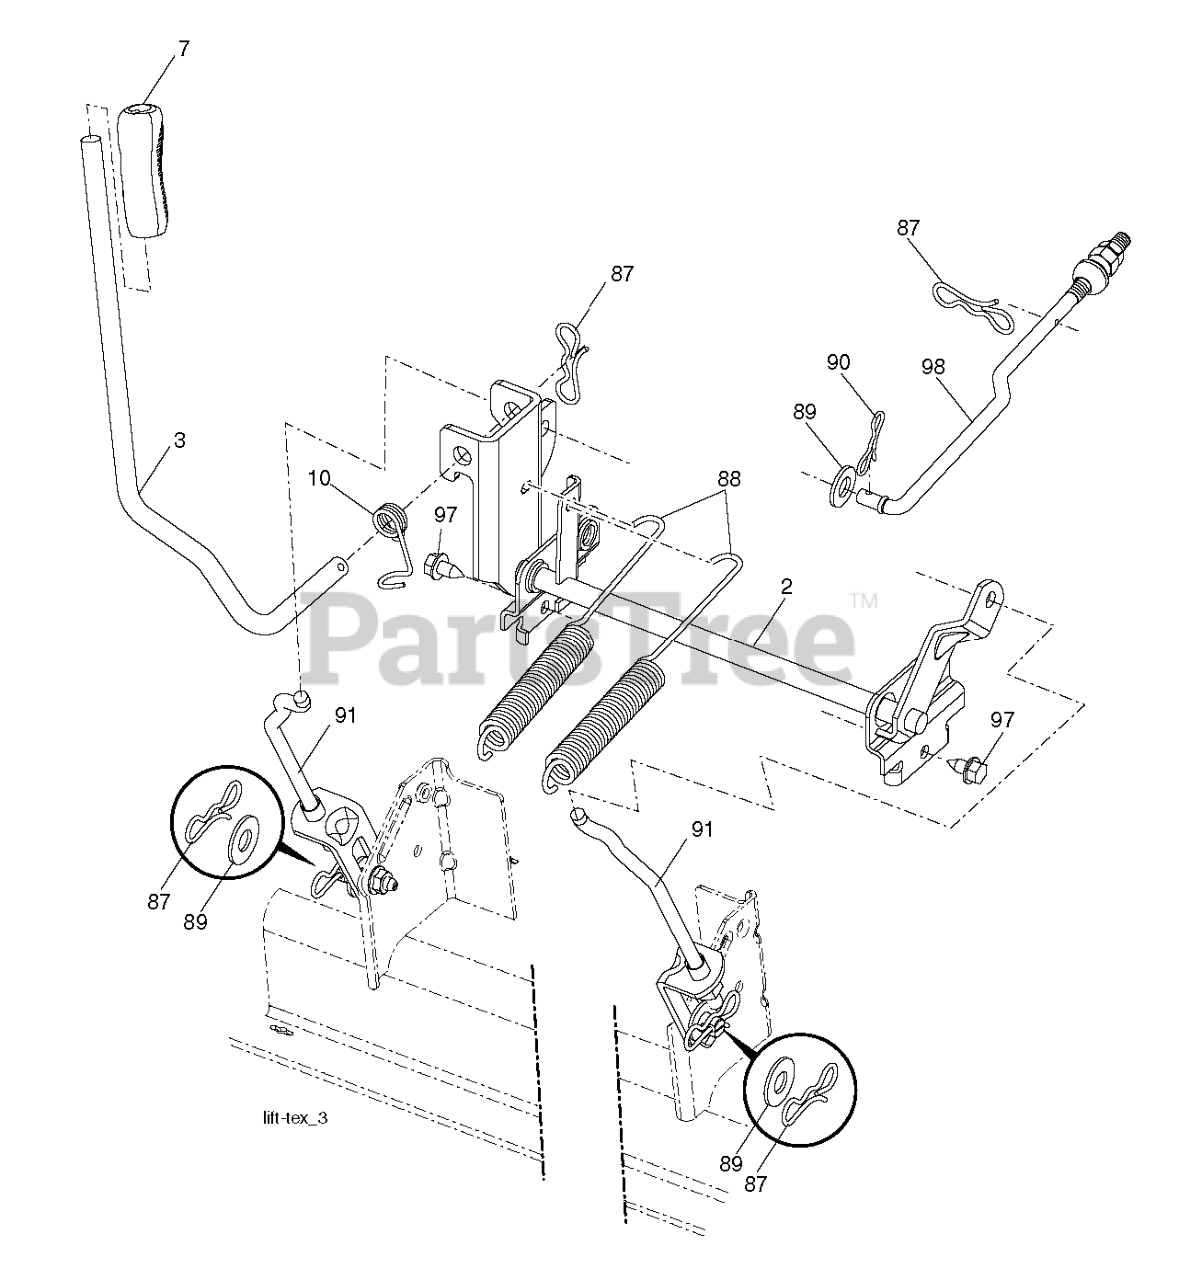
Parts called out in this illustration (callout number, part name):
2	SHAFT.ASM.CROSS.LIFT
3	LEVER.LIFT.HANDLE.LT
7	GRIP.HANDLE.LIFT.PVC.BLACK
10	SPRING.TORSION.LIFT.HANDLE
87	PIN.COTTER.7/16.BOW TI.
88	SPRING.LIFT.ASSIST
89	WASHER.CLEAR.ZINC
90	PIN.COTTER.5/16.BOW TI
91	LINK.ASM.LIFT.REAR
97	SCREW, 3/8-16X3/4
98	LINK.ASM.SUSP.FRONT.MWR.10.5
